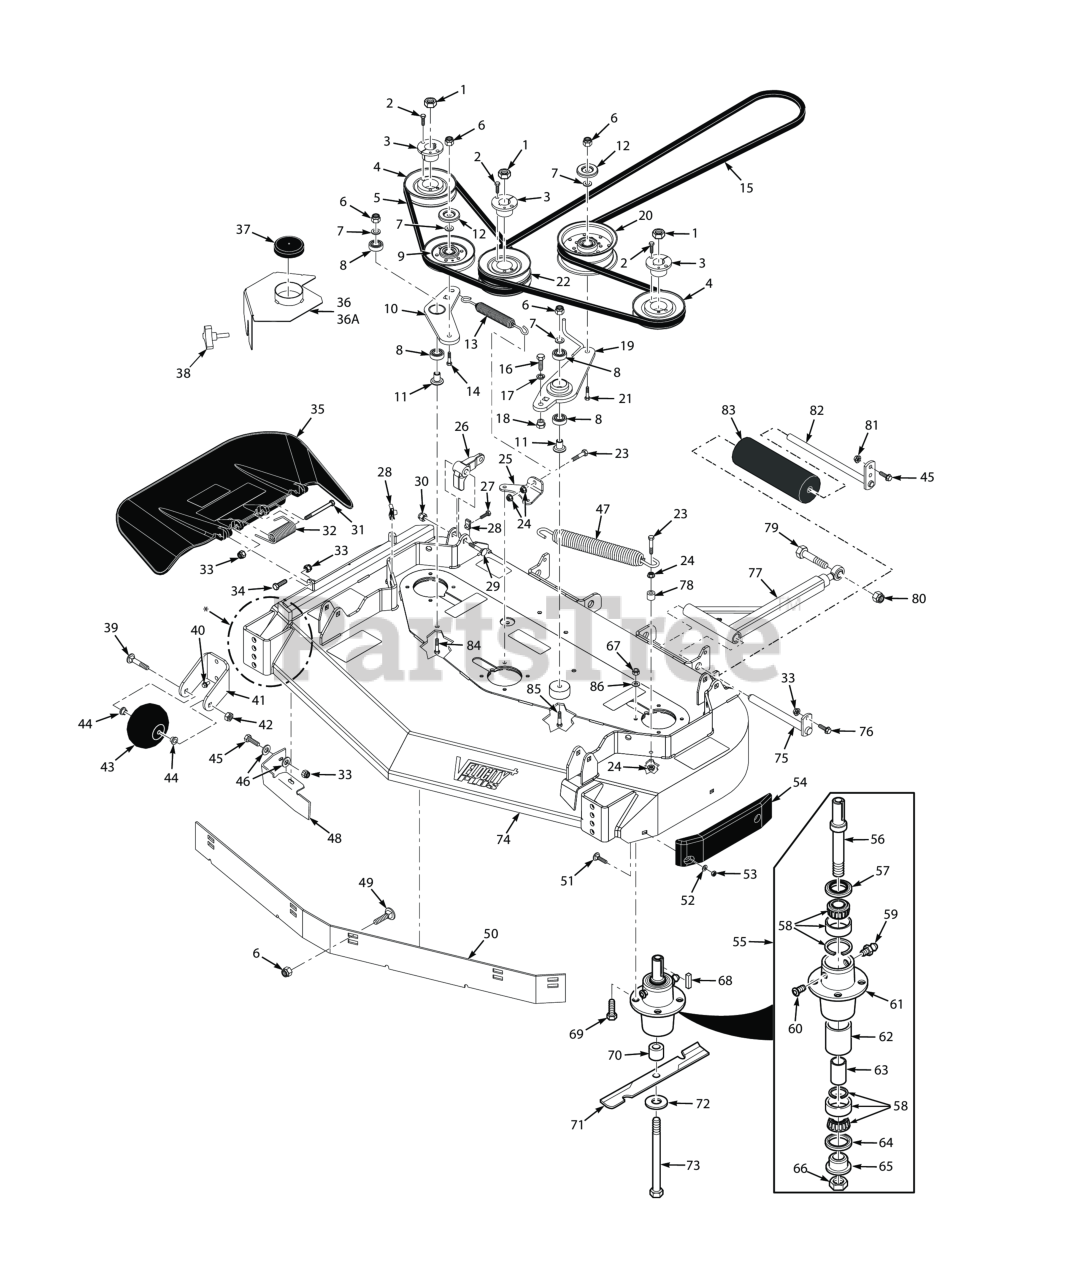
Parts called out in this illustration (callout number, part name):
1	Hex Locknut, Elastic Stop, 3/8-16
2	Bolt, Hex Head 1/4-20 x 1" Grade 8 Black
3	Hub, Tapered 1-1/8" Bore
4	Pulley, 5.13" Dia. - 48V
5	Belt, R.H. Cutter Deck
6	HEX NUT, ELASTIC STOP LOCK, 3/8-16
7	Flatwasher, 3/8 (.391 x .938 x .105 HD) Grade 8
8	BEARINGS, BALL, NEUTRAL RETURN
9	IDLER PULLEY, "V" GROOVE
10	ldler Arm Assembly, R.H. Drive
11	Pivot, Idler Short
12	Quick Pin, 5/16" Dia.
13	Spring, Idler R.H.
14	Capscrew, Hex Head 3/8-16 x 2.0"
15	Belt, Cutter Deck Drive (48V)
16	Bolt, Hex Head 7/16-14 x 1"
17	Lockwasher, 7/16� Spring
18	Boss, Spring Anchor - LH
19	Idler Arm Assy.
20	Pulley, Idler 5" Dia.
21	Bolt, Hex Head 3/8-16 x 3" - 52"
22	Pulley, Double Groove
23	Bolt, Hex Head 3/8-16 x 1-1/2" Grade 8 Black
24	NUT, 3/8-16 SERRATED FLANGE HEX HEAD
25	Bracket, Spring Anchor RH (48V)
26	Lever, Deck Level
27	Bolt, Hex Head 3/8-16 x 2" Special Lock
28	U-Nut, 3/8-16 (short)
29	Bolt, Carriage 7/16-14 x 2-1/4"
30	HEX LOCKNUT, ELASTIC STOP, 7/16-14
31	Bolt, 5/16-18 x 4-3/4" Hex Head
32	Spring, Discharge Chute
33	HEX NUT, ELASTIC STOP LOCK, 5/16-18
34	Bolt, Hex Head 5/16-18 x 1-1/2" - Front
35	Discharge Chute Assembly - 48V
36	Belt Cover Weldment RH
36	Belt Cover Weldment LH
38	Knob, w/stud 3/8-16 x 1-1/4"
39	Bolt, Hex Head 3/8-16 x 3-1/2"
40	Capscrew, 3/8-16 x 1.0" Serrated Flange Hex Hd
41	Bracket, Anti-Scalp Wheel
42	Bolt, Hex Head 3/8-16 x 1" Ser. Flg.
43	Bolt, Carriage 3/8-16 x 4"
44	Bushing, .376" I.D. Oilite
45	Bolt, Heax Head 5/16-18 x 1" (48V / 52V)
46	Flatwasher, 5/16-.375 x .875 x .083 (35BV & 37BV-EFI)
47	Spring, L.H. Deck Drive
48	Turbo Baffle - 48V / 52V
49	Carriage Bolt, 3/8-16 x 1.0"
50	Baffle Custom-Cut, 48V (7-Position)
51	Bolt, 5/16-18 x .75 RHSN Carriage
52	Flatwasher, 5/16-.344 x .688 x .065 (48V / 52V)
53	Nut, Center Lock, 5/16-18(32)
54	Pad, Deck Wear
55	Cutter Spindle Assembly
56	Spindle Shaft, Tapered Brng
57	SEAL, 2.00 O.D. X 1.50 BORE
58	Tapered Bearing Set (Two Bearings W/Race)
59	GREASE FITTING, STR. 1/4-28 SELF TAP.
60	RELIEF FITTING, TAPERED BEARING SPINDLE
61	Housing, Spindle
62	Spacer, Outside, Cutter Spindle
63	SLEEVE, CUTTER SPINDLE
64	Seal, 2.00" O.D. x 1.625" Bore
65	SPINDLE BUSHING, BOTTOM
66	Nut , Spec ial 1 -1/ 1 6 - 1 8
67	Lock Nut, 5/16-18 Elastic Stop Grade 8
68	Key, 1/4 x 1/4 x 2.0"
69	Bolt, Hex Head 5/16-18 x 1-3/4" Grade 8
70	Spacer, Spindle Bottom
71	Cutter Blade, 16-1/2" (48V)
72	Flatwasher, 5/8-.688 x 1-3/4 x .134 HD
73	BOLT, HEX HEAD, 5/8-11 X 9-1/2 GR.5
74	Cutter Deck Velocity Plus
75	Shaft Weldment, Pusharm
76	Bolt, Heax Head 5/16-18 x 1" (48V / 52V)
77	Push Arm (Includes 64,60,62)
78	SPACER, IDLER
79	BOLT, HEX HEAD 5/8-11 X 4-1/2"
80	HEX LOCKNUT, ELASTIC STOP, 5/8-11
81	Nut, Flange Head Elastic Stop 5/16-18
82	Shaft Weldment, Guide Roller
83	Wheel, Anti-ScalpRelief Fitting, Tapered Spindle
84	Bolt, Hex Head 3/8-16 x 2-1/4" - 61"
85	Capscrew, Hex Head 3/8-16 x 3.25"
86	Lockwasher, 5/16 (.317 x .586 x .078) Helical Spring
